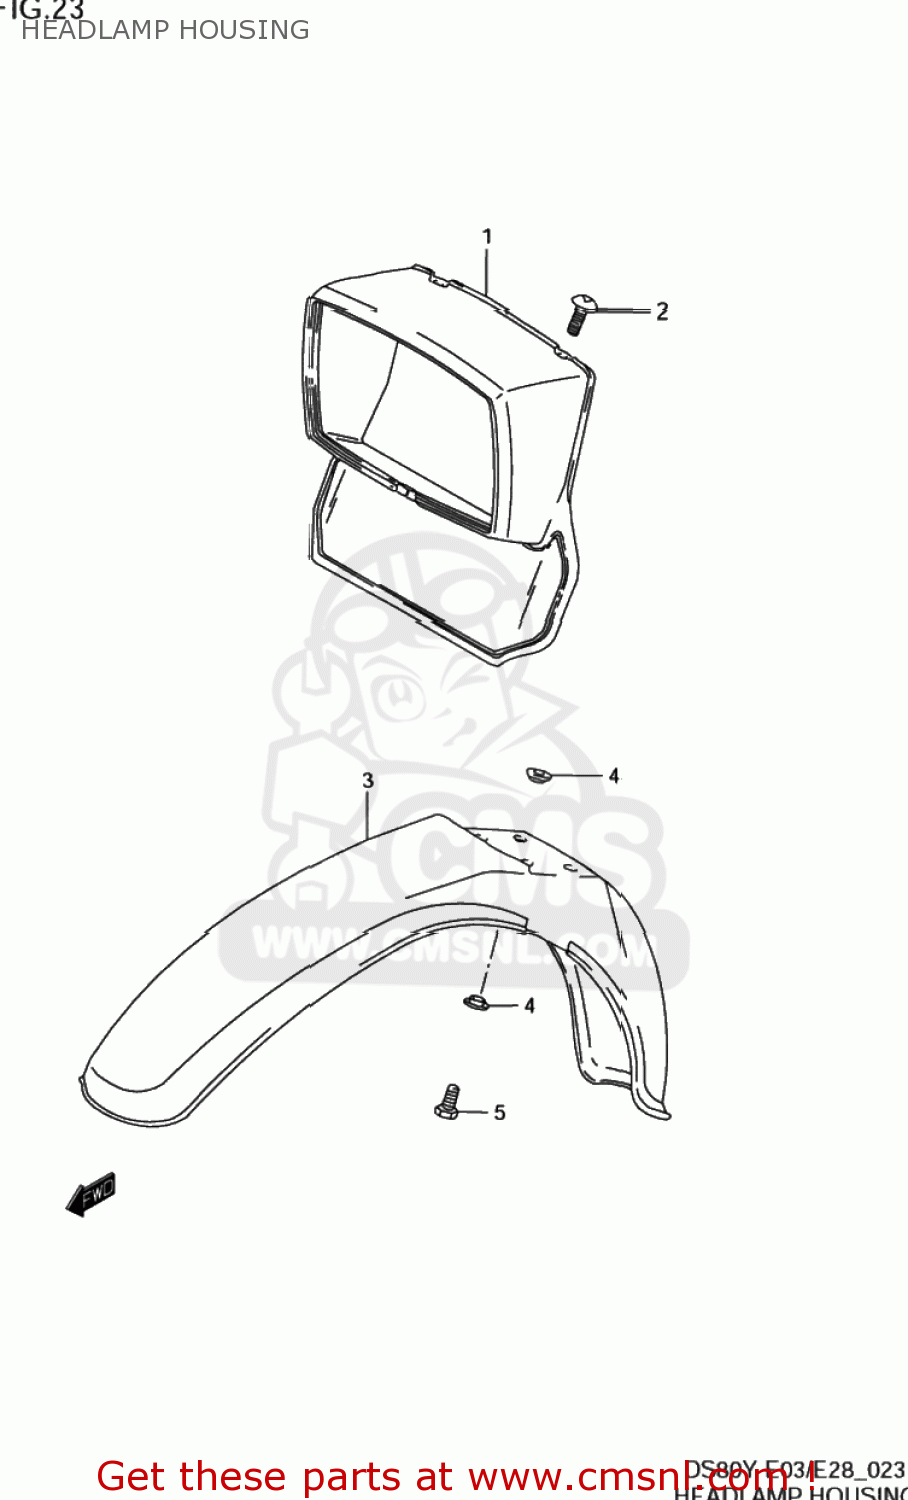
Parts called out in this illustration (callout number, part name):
1	HOUSING,HEADLAMP
2	SCREW 6X12
3	FENDER,FR
4	WASHER
5	BOLT
